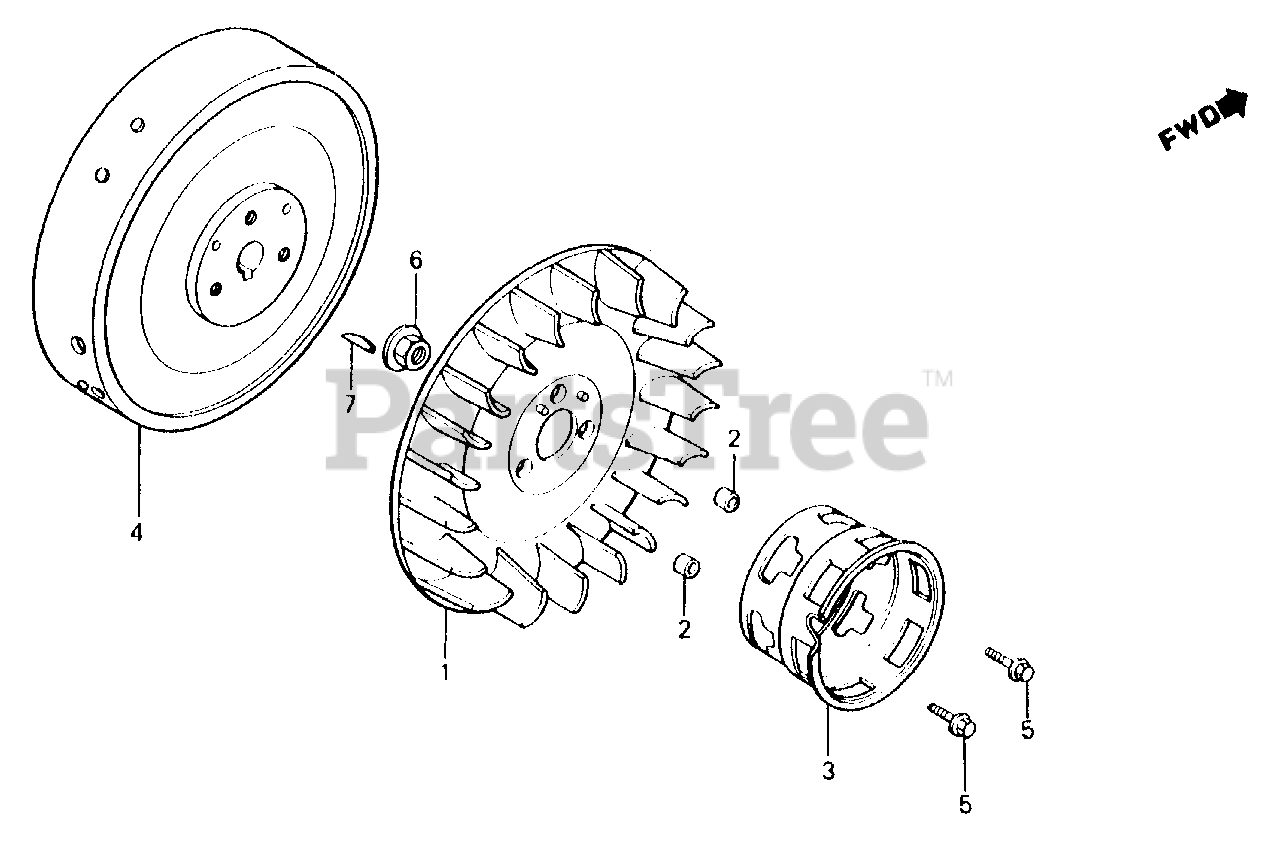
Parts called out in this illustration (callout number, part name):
1	FAN, COOLING
2	COLLAR, FAN
3	PULLEY, STARTER
5	BOLT, FLANGE (6X16)
6	NUT, SPECIAL (16MM)
7	KEY, SPECIAL WOODRUFF (25X18)
